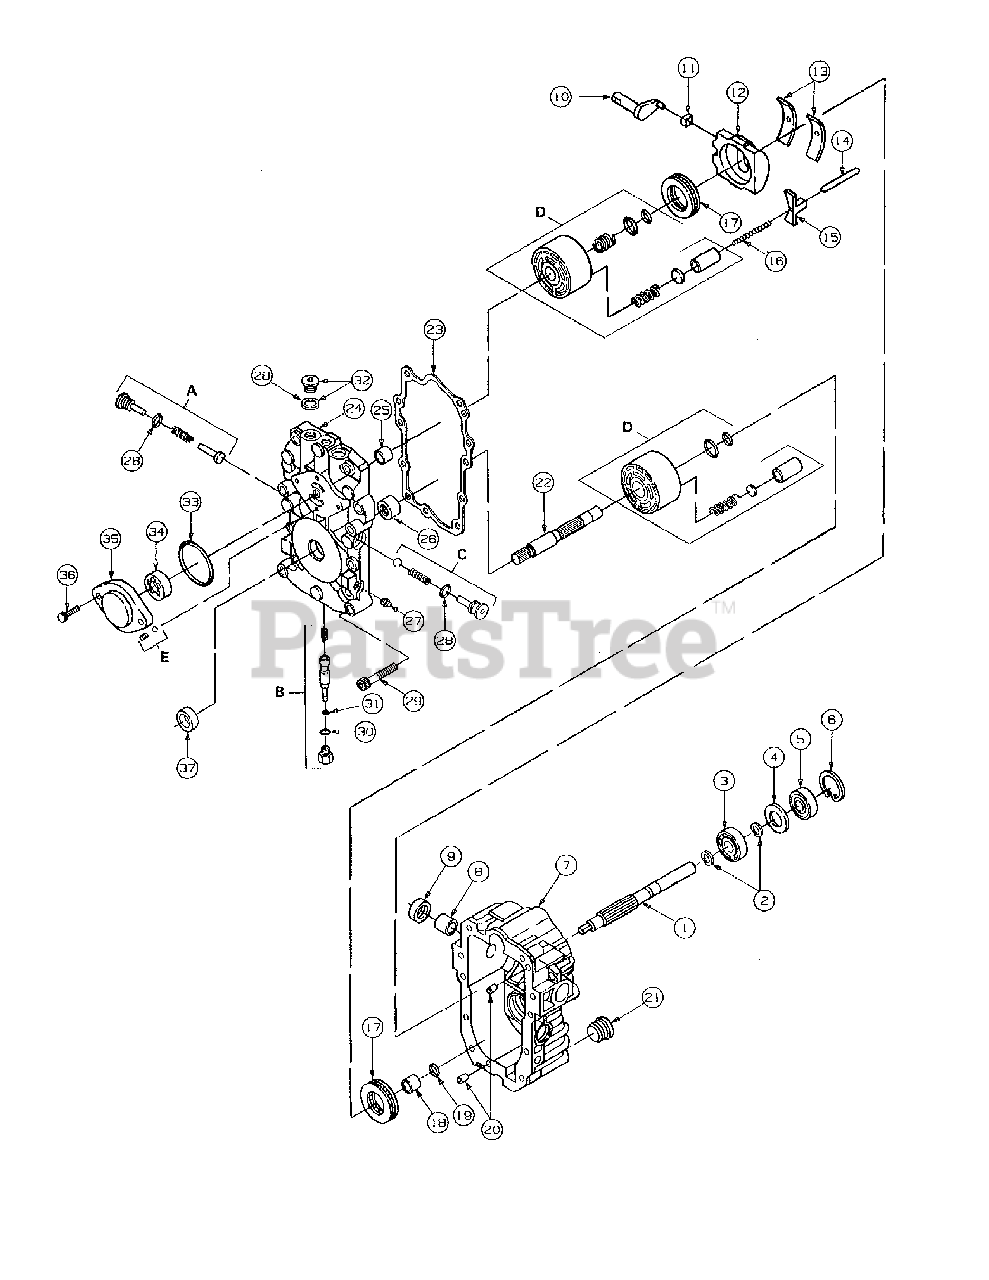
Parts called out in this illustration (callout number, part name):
1	Shaft, Pump
2	Ring, Retining
3	Bearing, Ball
6	Ring, Retaining
7	Housing Assembly
8	Bearing, Journal
10	Arm, Trunnion
13	Bearing Cradle
15	Leveler, Swashplate
16	Spring, Leveler
17	Bearing, Thrust
18	Bearing, Journal
19	Washer, Thrust
22	Shaft, Motor
23	Gasket, Center Section
24	Center Secton Assembly
25	Bearing, Journal
26	Bearing, Needle
29	Screw, Socket Hd
34	Gerotor Assembly
35	Housing, Charge Pump
36	Screw, Socket Hd
A	Kit, Orificed Check Valve
B	Kit, Bypass Valve
C	Kit, Check Valve
D	Kit, Cylinder Block
E	Kit, Charge Relief Valve
